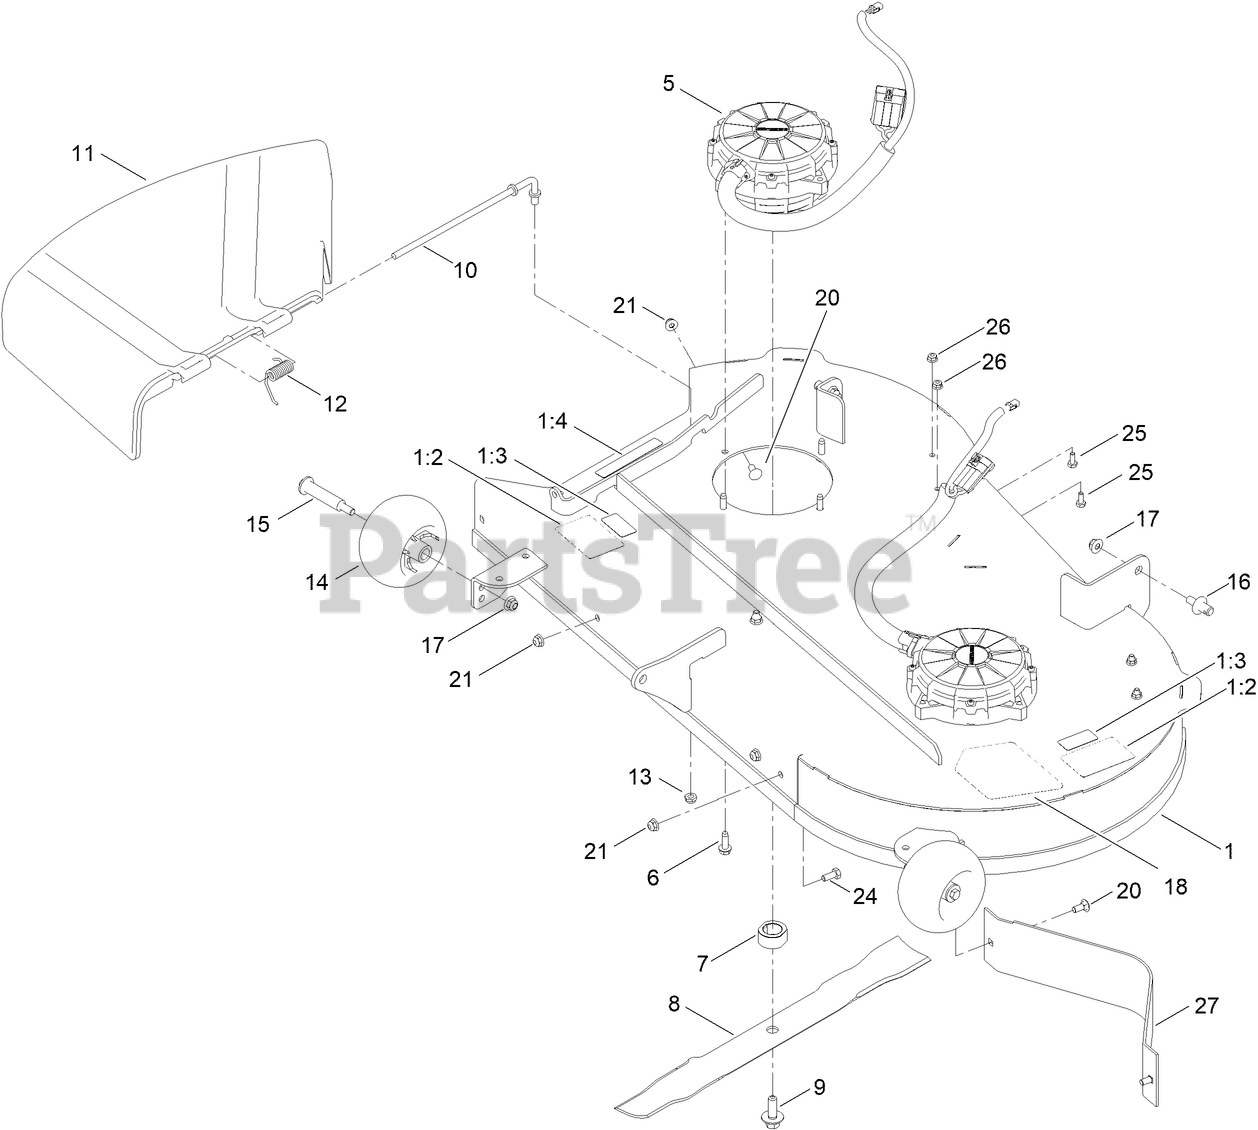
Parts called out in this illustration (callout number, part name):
1	42 IN DECK AND DECAL ASM
1:2	DECAL-DANGER, DECK
1:3	DECAL-NO SPRAY
1:4	DECAL-DANGER
5	MOTOR-DECK
6	SCREW-THD ROLL, HWH
7	DRIVER-BLADE
9	BOLT-BLADE, SEMS
10	ROD-PIVOT
11	DEFLECTOR-DISCHARGE
12	SPRING-TORSION
13	NUT-HEX
14	ROLLER-SCALP, ANTI
15	BOLT-SHOULDER
16	PIN-DECK
17	NUT-HF, NI
18	DECAL-IRON FORGED, 42
20	BOLT-CARR
21	NUT-HF
24	SCREW-HH
25	SCREW-HH
26	NUT-FLANGE, NI
27	DEFLECTOR-42"
